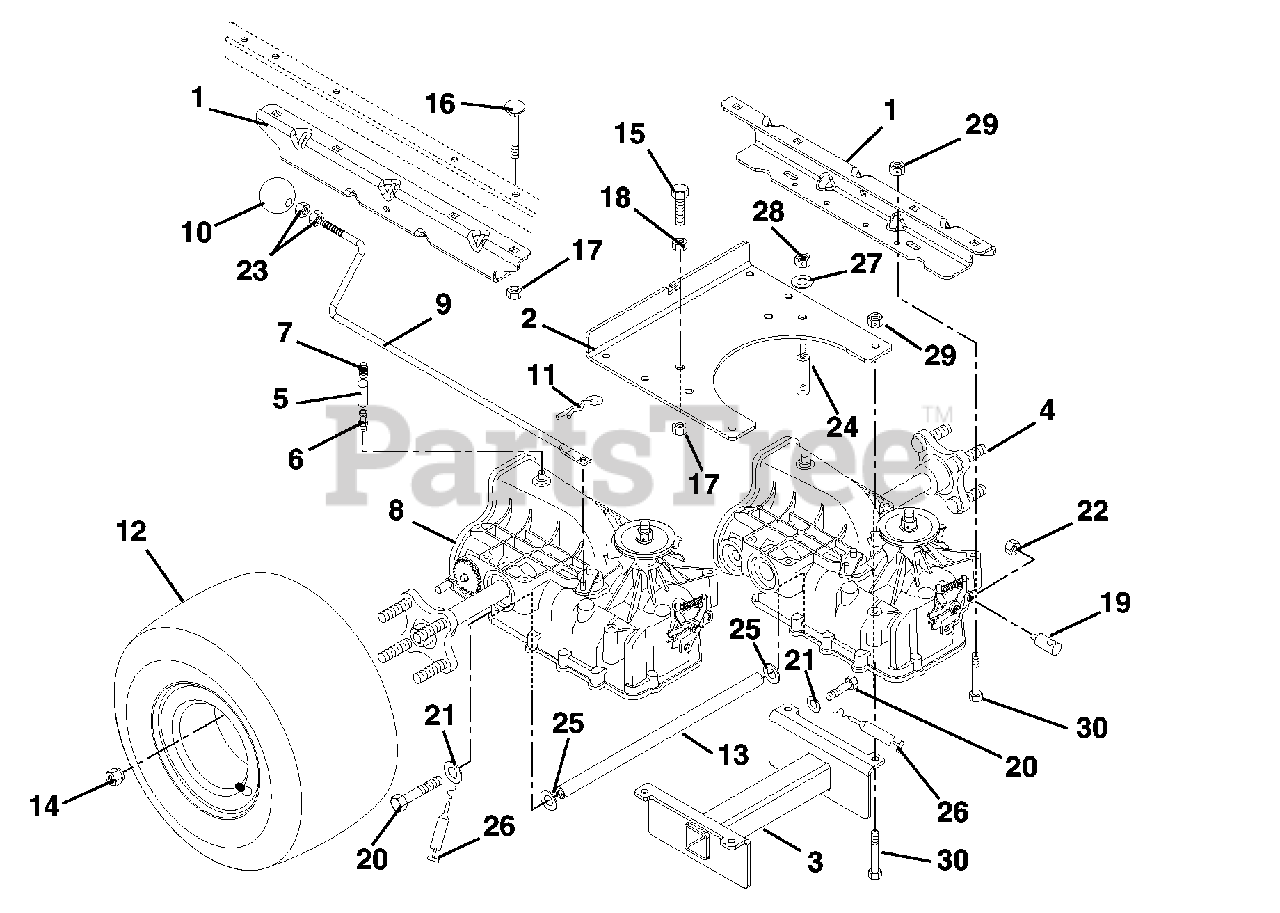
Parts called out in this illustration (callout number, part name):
1	BKT-TRANS AXLE
2	BKT-TRANS AXLE SUPPORT
3	WLDMT-TRANS AXLE BRACE
5	HOSE - VENT
6	FTG-STR .50 O-RING
7	CAP-VENT .50
9	ROD-DUMP IZT
10	KNOB, BALL 5/16-18 X 1.5
11	PIN-HAIR, ENDRIES #25 YWZC
12	ASSY-TIRE 9.5X18-2PLY
12	ASSY-TIRE 8.5X18 2PLY
13	ROD-AXLE BRACE
14	NUT-LUG .50-20 YWZC
15	@BLT-HEX .38-16X3.00 GR5 YWZC
16	BLT-RDHDSQNK .38-16X2.25 G5BZ
17	NUT-LK-TOP-FLG .38-16 BLKZC
18	@NUT-SPNLK-FLG .375-16 YWZC
19	ROD PIVOT YWZC
20	@BLT-HEX .31-18X2.50 GR5 YWZC
21	@WSHR-LK .31X.078 REG YWZC
22	NUT-LK-TOP-FLG .31-18 BLKZC
23	NUT- JAM .312-18 YWZC
24	SHOULDER STUD
25	WSHR-FL-STL .328X.87X.179 YWZC
26	ADHSV SEALANT (BLUE) 250 ML
27	@WSHR-LK .38X.094 REG YWZC
28	@NUT-HEX .38-16 YWZC
29	@NUT-LK-NYL .312-18 YWZC
30	@BLT-HEX .31-18X2.75 GR5 YWZC
